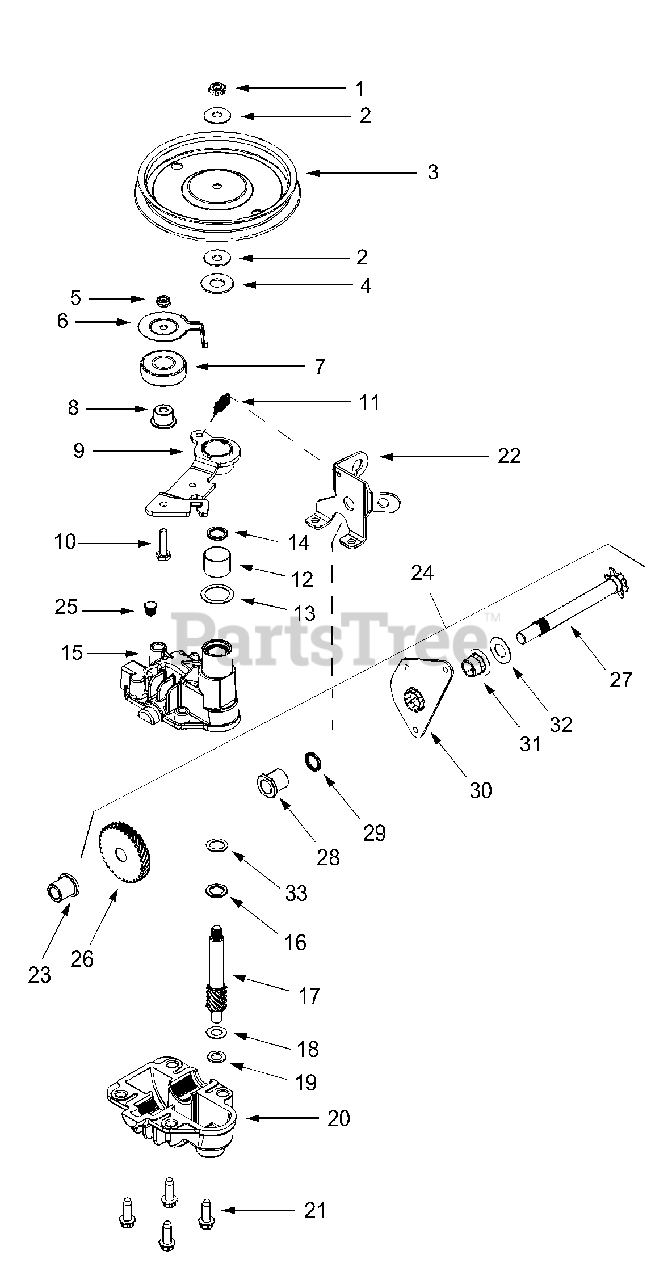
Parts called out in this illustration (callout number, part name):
1	Hex Jam Nut, 5/16-24
2	Bell Wash. .325 x .930 x .045
4	Fl. Wash. .510 x 1.120 x .060
5	Hex Jam Nut , 1/4-28
7	Bearing
8	Flange Spacer
9	Idler Bracket Assembly
10	Hex Cap Screw 1/4-28 x 1.00 Gr. 5
11	Extension Spring
12	Bearing Sleeve
13	Fl. Wash. .885 x 1.145 x.030
14	Oil Seal
15	Upper Housing Assembly
16	Thrust Wash. .504 x .700 x .030
17	Pinion Shaft, 10 T.
18	Thr. Wash. 3/8 x .70 x .030
19	Thr. Wash. .388 x .625 x .062
20	Lower Housing Assembly
21	Hex Screw 1/2-20 x .75
24	Shaft Assembly
27	Output Shaft, 6 T.
28	Flange Bearing
29	Oil Seal
30	Pivot Bracket
31	Flange Bearing
